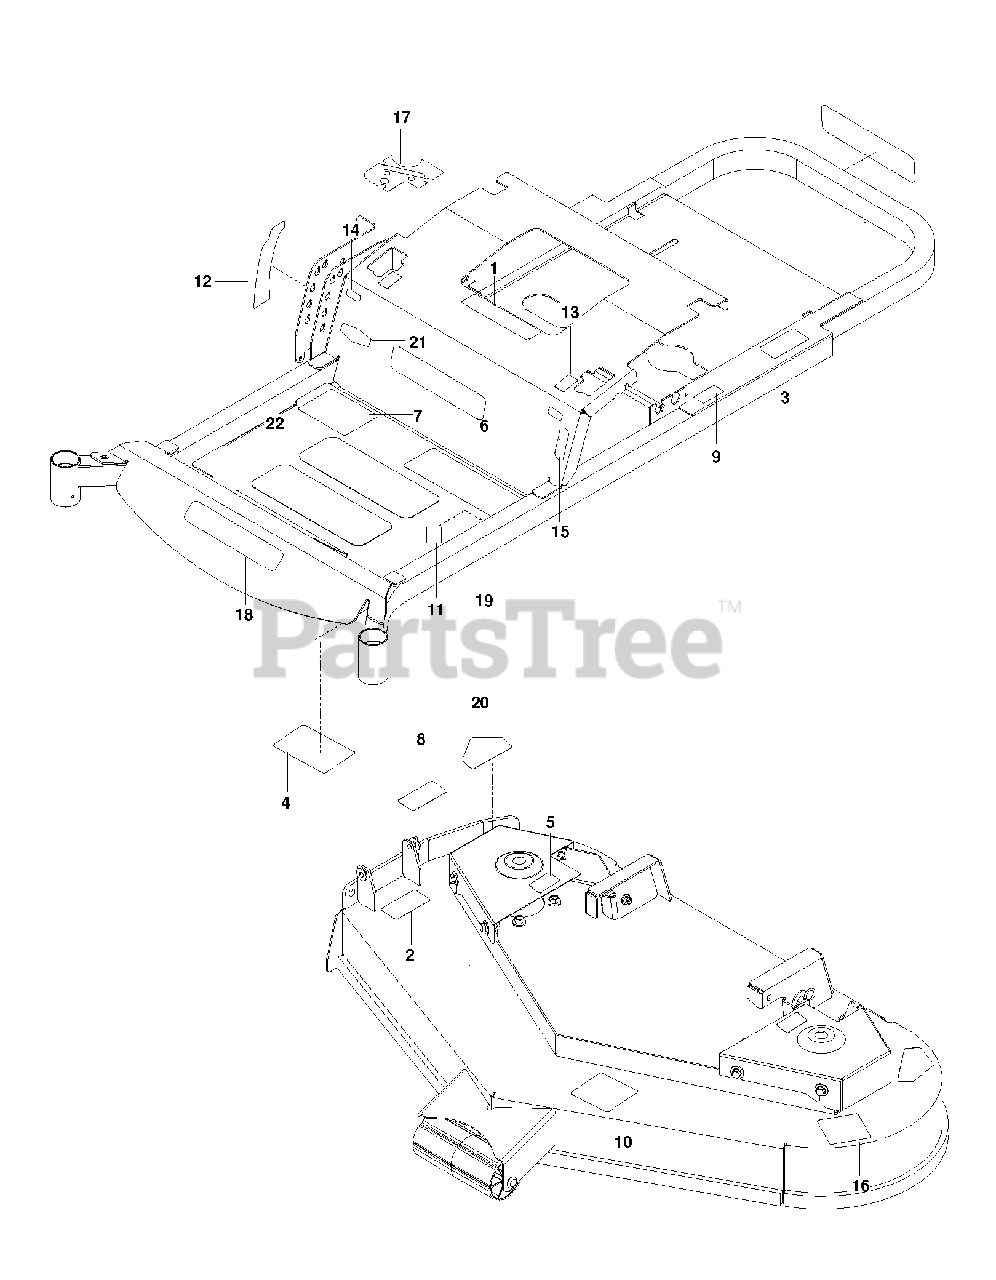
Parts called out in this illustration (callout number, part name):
2	DECAL, EURO SEVERING
3	DECAL, DO NOT MOUNT
4	DECAL, SERVICE
6	DECAL, SAFETY WARNING
7	DECAL, WARNING
8	DECAL, DANGER
9	DECAL, ECM, AUSTRALIA
10	DECAL, BELT ROUTING
20	DECAL, CPSC
22	ANTI-SKID PAD
